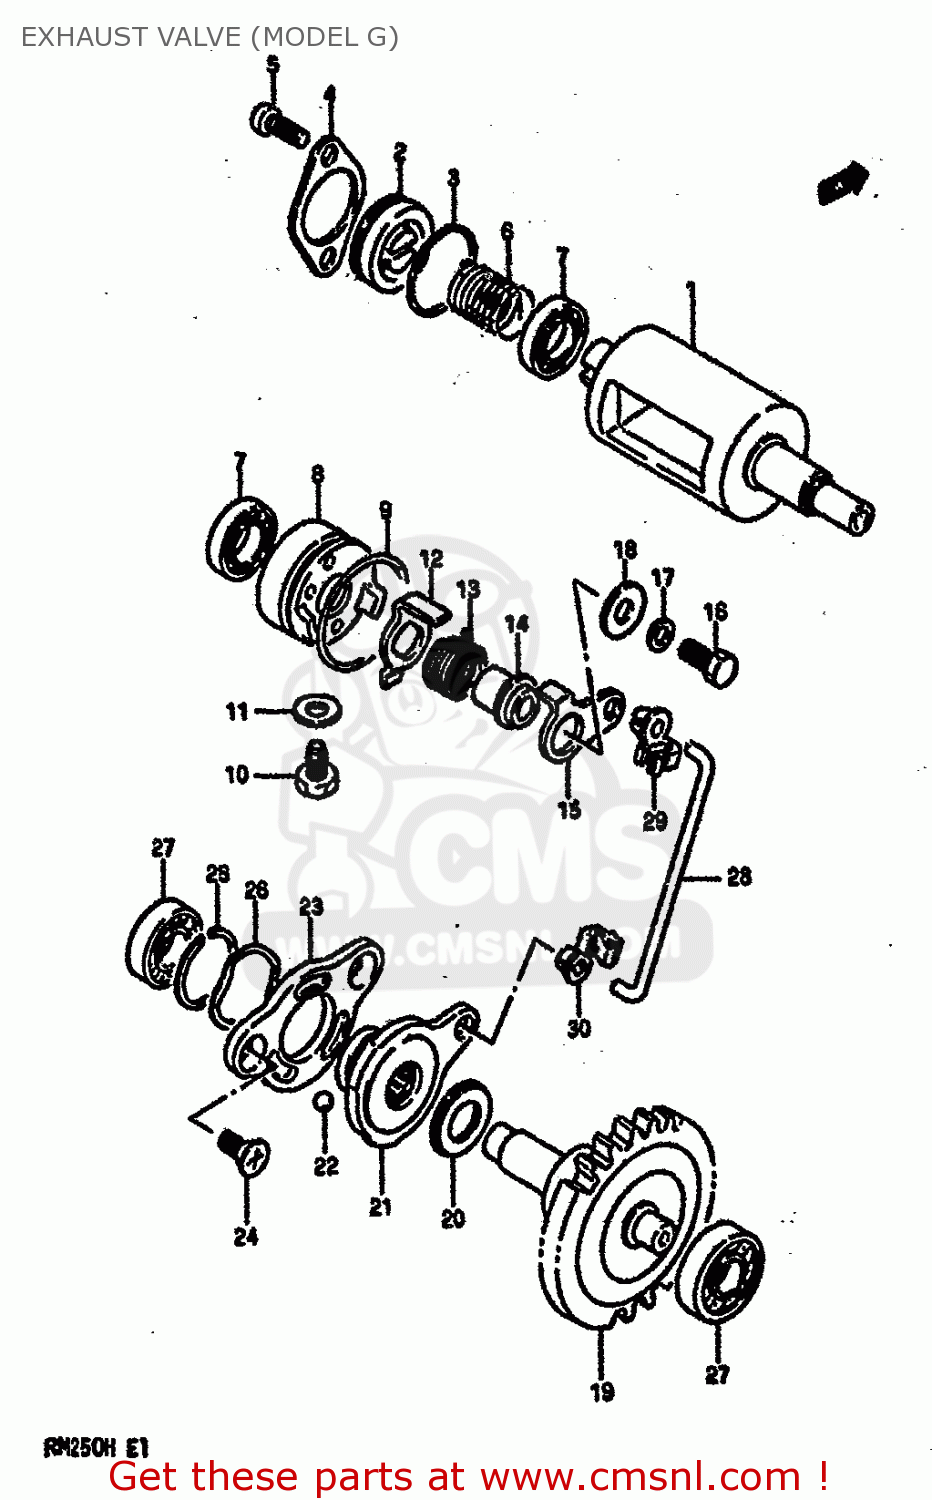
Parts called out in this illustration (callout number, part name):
1	VALVE,EXHAUST
2	CAP,EXHAUST VALVE
3	O RING(D:1.9,ID:22.6)
4	RETAINER,EXHAUST VALVE
5	SCREW
6	SPRING
7	BEARING
8	HOLDER,EXHAUST VALVE
9	O RING(D:2.4,ID:27.7)
10	BOLT
11	GASKET(6.2X11X1).2 (NAS)
12	LEVER,EXHAUST VALVE NO.2
13	SPRING
14	SPACER,EXHAUST VALVE
15	LEVER,EXHAUST VALVE NO.1
16	BOLT
17	LOCK WASHER
18	WASHER (5.5X16X1.2)
19	GOVERNOR ASSEMBLY,EXHAUST
20	BEARING(10X22X2.8)
21	ACTUATOR,EXHAUST VALVE
22	BALL
23	STATOR,EXHAUST VALVE ACTUATOR
24	SCREW(5X10)
25	CIRCLIP
26	WASHER
27	BEARING(8X22X7)
28	ROD,EXHAUST VALVE
29	BUSH,EXHAUST VALVE ROD NO.1
30	BUSH,EXHAUST VALVE ROD NO.2
